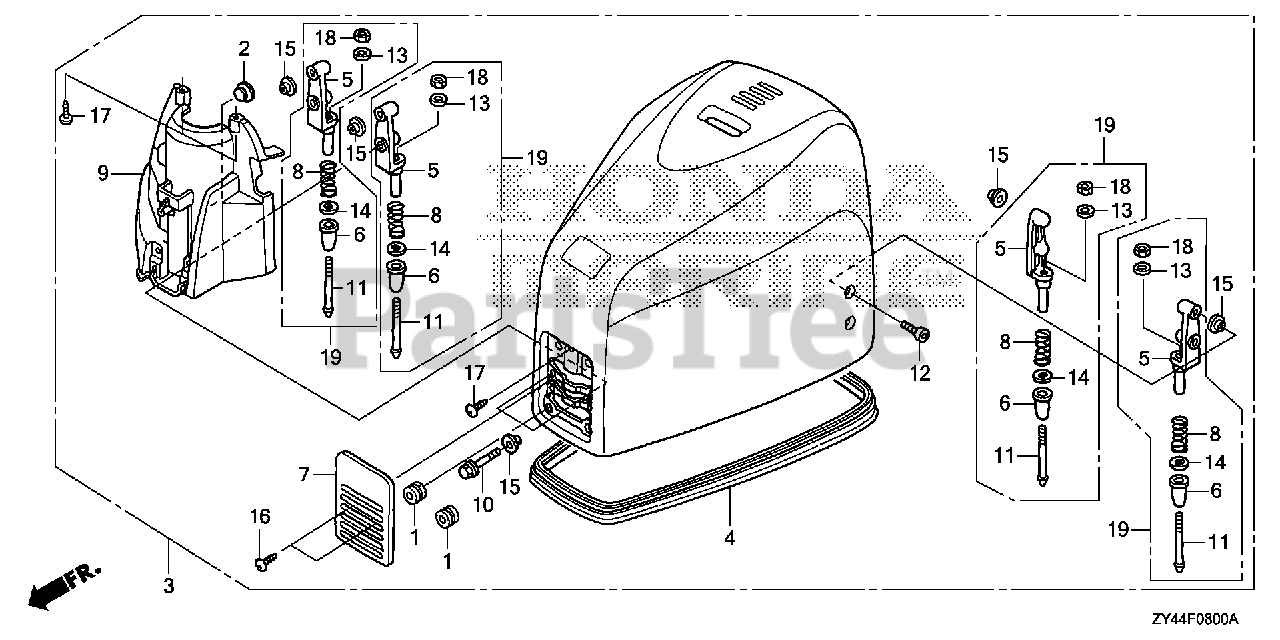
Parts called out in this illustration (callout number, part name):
1	GROMMET, AIR CLEANER HOUSING
2	GROMMET, WIRE
3	COVER ASSY., ENGINE *NH282MU* (OYSTER SILVER METALLIC-U)
4	SEAL, ENGINE COVER
5	BRACKET, HOOK
6	DAMPER, HOOK
7	COVER, FR. *NH282MU* (OYSTER SILVER METALLIC-U)
8	SPRING, LOCK ADJUSTER
9	DUCT, ENGINE COVER
10	BOLT, FLANGE (6X20)
11	BOLT, COVER LOCK
12	BOLT, SOCKET (6X16)
13	WASHER, PLAIN (6MM)
14	WASHER, PLAIN (12MM)
15	COLLAR, DISTANCE (6.5X9X3)
16	SCREW, TAPPING (4X10)
17	SCREW, TAPPING (4X10)
18	NUT, HEX. (6MM)
19	HOOK KIT, COVER
